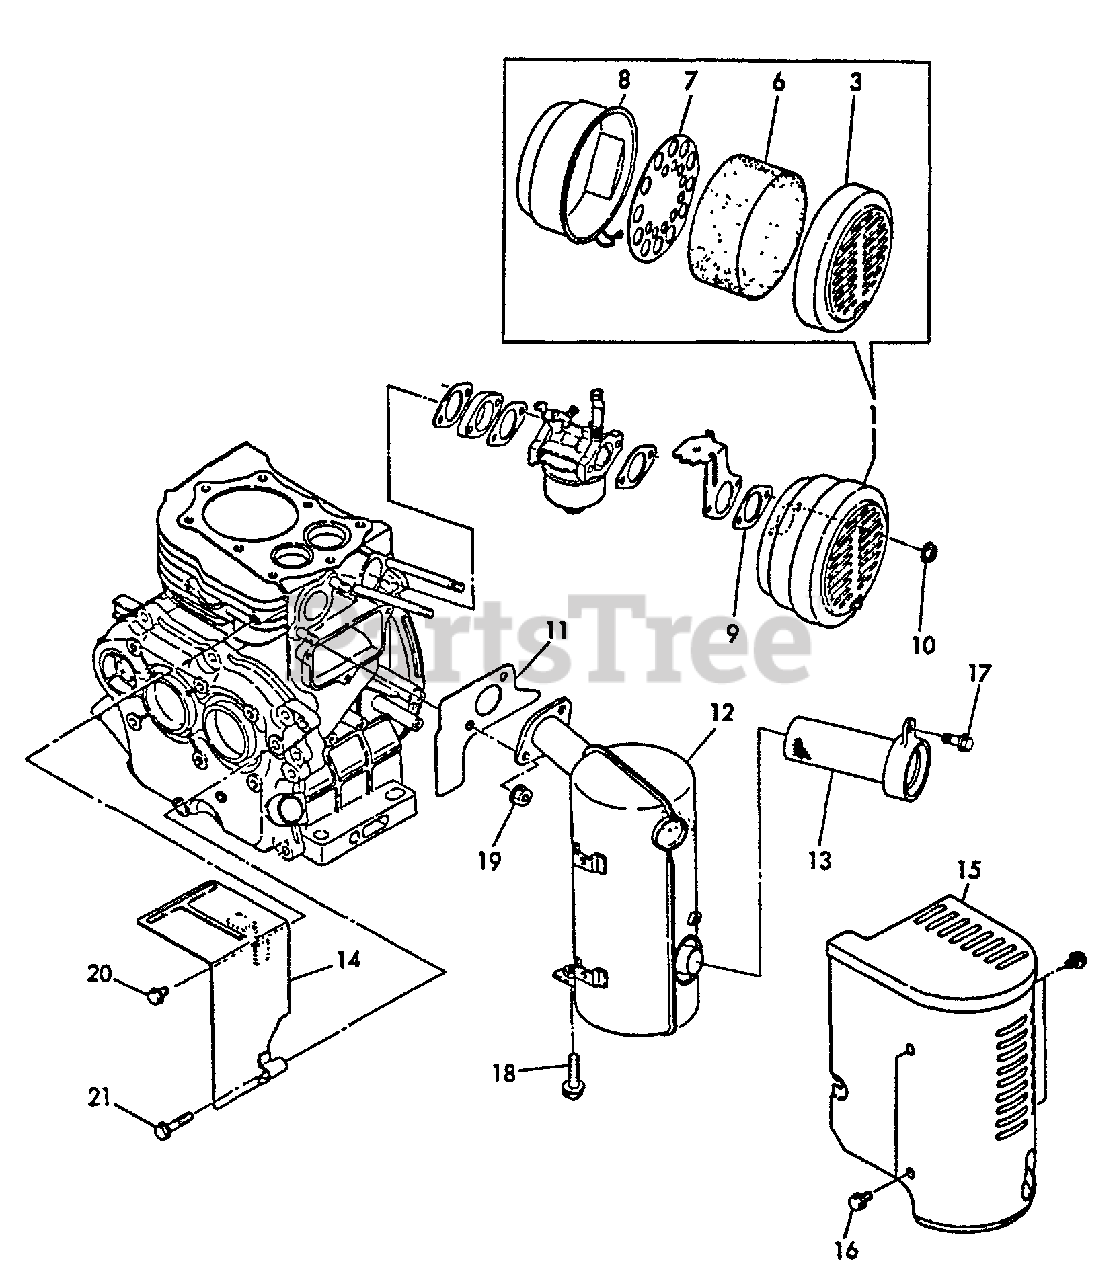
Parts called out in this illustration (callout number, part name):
1	CLEANER ASSY, AIR
3	CASE, AIR FILTER
6	FILTER, AIR
7	HOLDER, ELEMENT
8	CAP, AIR FILTER
10	U-NUT M6
11	GASKET, EXHAUST
12	MUFFLER
13	SCREEN, SPARK ARRESTER
14	PLATE, GUIDE
15	COVER, MUFFLER
16	BOLT - 6×8 -- PLATED
17	BOLT - 6×10 -- PLATED
18	BOLT - 8×30 -- PLATED
19	U-NUT M8
20	BOLT - 6×8 -- PLATED
21	BOLT - 6×30
